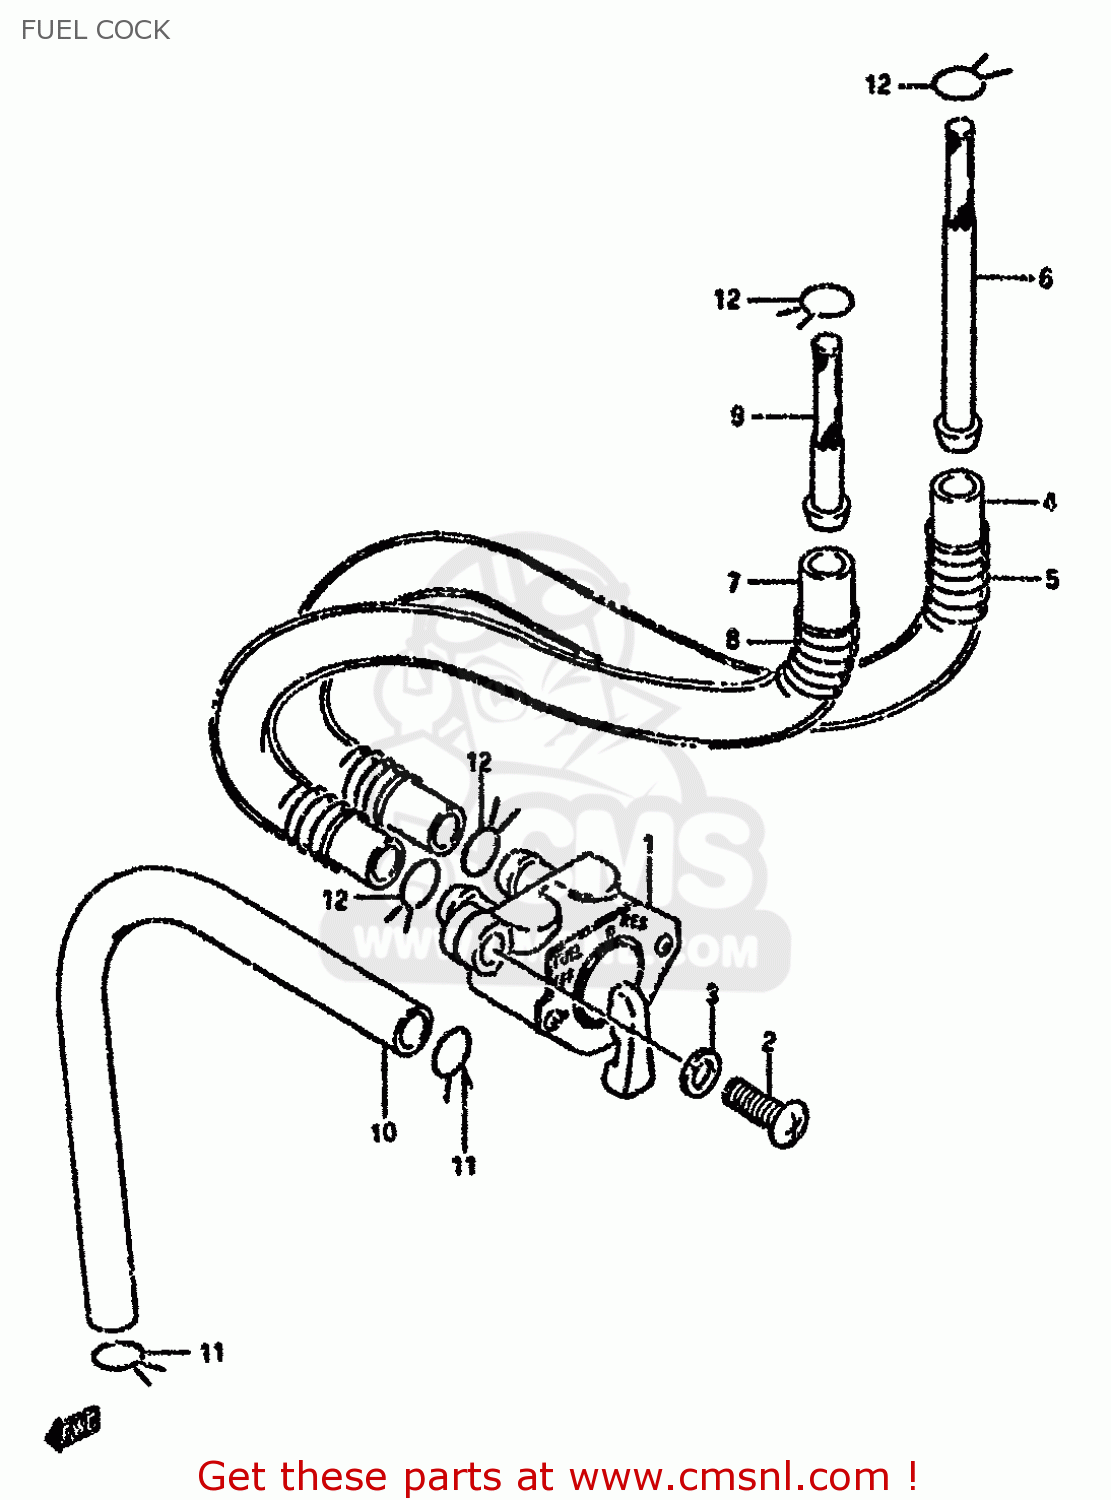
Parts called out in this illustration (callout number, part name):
1	COCK ASSY,FUEL
2	SCREW
3	WASHER,LOCK
4	HOSE(7X10.2X600)
5	SPRING
6	FILTER,FUEL
7	HOSE 7X10.2X210
8	SPRING
9	FILTER,FUEL
10	HOSE(5X8.2X600)
11	CLIP
12	CLIP
